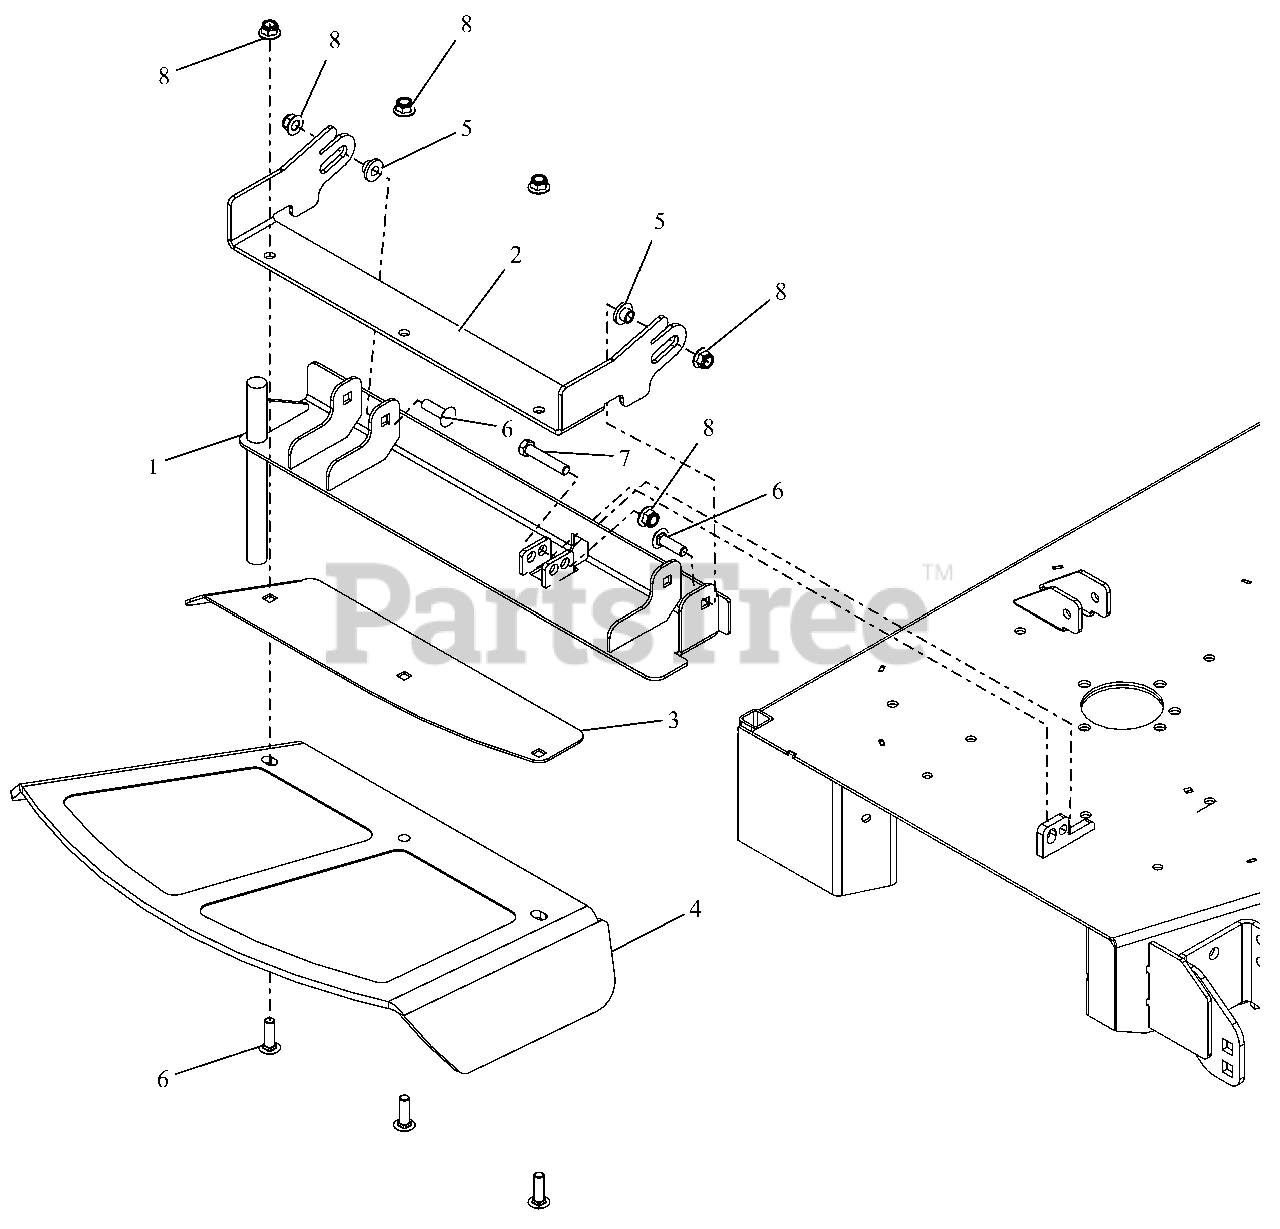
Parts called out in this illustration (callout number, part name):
1	48-60 DISCH CHT MTG WMT W/SAFE
2	48-60" CHUTE MTG BRKT - RED
3	48-60 DISCH CHUTE CLMP PLT-RED
4	CHUTE,48-60" FRMD RUBBER DISCH
5	BSHG-FLG .385X.500X.875X.406
6	@BLT-RHDSSQNK .38-16X1.25 G5YZ
7	@BLT-HEX .38-16X2.00 GR5 YWZC
8	@NUT-LK-NYL-FLG .38-16 YWZC
